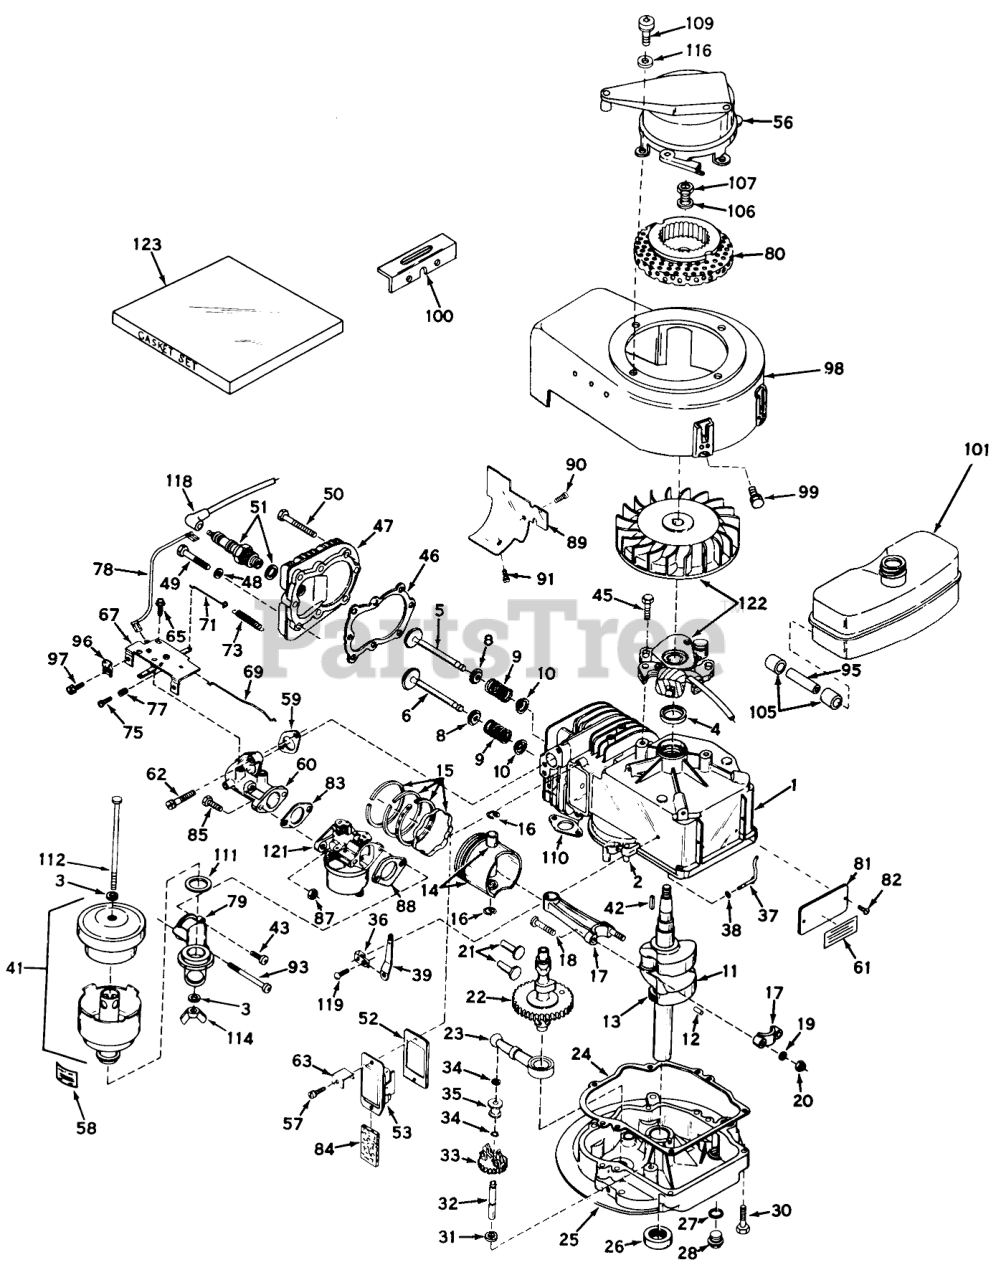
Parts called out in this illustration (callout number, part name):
1	Cylinder Assy. (Incl. Nos. 2 & 4)(Use with Model LAV30-30265G only)
1	Cylinder Assy. (Incl. Nos. 2 & 4)(Use with Model LAV35-40152G only)
2	Pin-Dowel
3	Washer Fibre
5	Valve, Intake (Standard)(Incl. Nos. 8, 9 & 10)
5	Valve, Intake (1/32" Oversize)(Incl. Nos. 8, 9 & 10) I
6	Valve, Exhaust (Standard)(Incl. Nos. 8, 9 & 10)
6	Valve, Exhaust (1/32" Overs.)(Incl. Nos. 8, 9 & 10)
8	Cap-Upper Valve Spring
9	Spring-Valve
10	Cap-Valve, Spring
11	Crankshaft Assy. (Incl. Nos. 12 & 13)(Use with Model LAV30-30265G only)
11	Crankshaft Assy. (Incl. Nos. 12 & 13)(Use with Model LAV35-40152G only)
12	Pin, Groove
13	Gear, Crankshaft
14	Piston & Pin Assy. (Standard)(Incl. 2 of No. 16)(Use with Model LAV30-30265G only)
14	Piston & Pin Assy. (.010 Oversize)(Incl. 2 of No. 16)(Use with Model LAV30-30265G only)
14	Piston & Pin Assy. (.020 Oversize)(Incl. 2 of No. 16)(Use with Model LAV30-30265G only)
14	Piston & Pin Assy. (Standard)(Incl. 2 of No. 16)(Use with Model LAV35-40152G only)
14	Piston & Pin Assy. (.010 Oversize)(Incl. 2 of No. 16)(Use with Model LAV35-40152G only)
14	Piston & Pin Assy. (.020 Oversize)(Incl. 2 of No. 16)(Use with Model LAV35-40152G only)
15	Ring Set, Piston (Std.)
15	Ring Set, Piston (.010 o.s.)
15	Ring Set, Piston (.020 o.s.)
15	Piston Ring Set Std.
15	Piston Ring Set .010 O.S.
15	Piston Ring Set .020 O.S.
16	Ring-Retaining, Piston Pin
17	Rod Assy., Connecting (Incl. Nos. 18, 19 & 20)
18	Bolt, Connecting
20	LOCKNUT
21	Lifter-Valve
22	Camshaft
23	Oil Pump ASM
25	Flange Assy., Mounting (Incl. Nos. 26, 27, 28 & 32)(LAV35-40152G only)
25	Flange Assy., Mounting (Incl. Nos. 26, 27, 28 & 32)(LAV30-30265G only)
28	Plug Oil Drain
30	Screw (1/4-20 x 1-1/4)
31	Washer-Flat
32	Shaft-Governor
33	Governor Gear ASM
34	Ring-Retaining
35	Spool-Governor
36	Clamp-Lever, Governor
37	Rod, Governor (Incl. No. 38)
38	Washer-Flat
39	Lever, Governor
41	Cleaner Assy., Air
42	Key Flywheel
43	KIT - SEAL & WIPER
47	CYLINDER HEAD
49	Screw
50	Screw
51	SPARK PLUG
53	Breather Assy. (Incl. Nos. 52 & 84)
56	Starter, Impulse
58	Decal, Air Cleaner
60	Pipe, Intake
61	480B GIL SNWTHWR O/
62	Screw, Fil. Hd. Sems
63	Retainer Clip
65	Screw (10-24 x 9/16)
67	Control Assy., Speed
69	Link, Throttle to Governor
71	Link, Governor Spring
73	Spring, Governor
75	Screw
77	Spring-Compression
78	Wire, Ground
79	Elbow, Air cleaner
80	Hub & Screen
81	IDENTIFICATION PLATE
84	Element-Breather
85	Screw (1/4-28 x 7/8)
87	Nut and Lock Washer (1/4-28)
89	Extension, Housing (Use with Model LAV35-40152G only)
90	Screw
95	Line, Fuel
96	Conduit
97	Screw (10-32 x 3/8)
98	Housing, Blower
99	Screw (1/4-20x19/32)
100	Bracket, Shroud
101	Tank, Fuel (Incl. No. 102)
102	Cap, Fuel Filler
105	Line-Fuel (8.62)
106	Washer
107	Nut, Flywheel
112	Bolt, Air Cleaner
114	Nut, Wing
118	Cover-Spark Plug
119	Screw
121	Carburetor
122	Magneto, Tecumseh
123	Gasket Set
